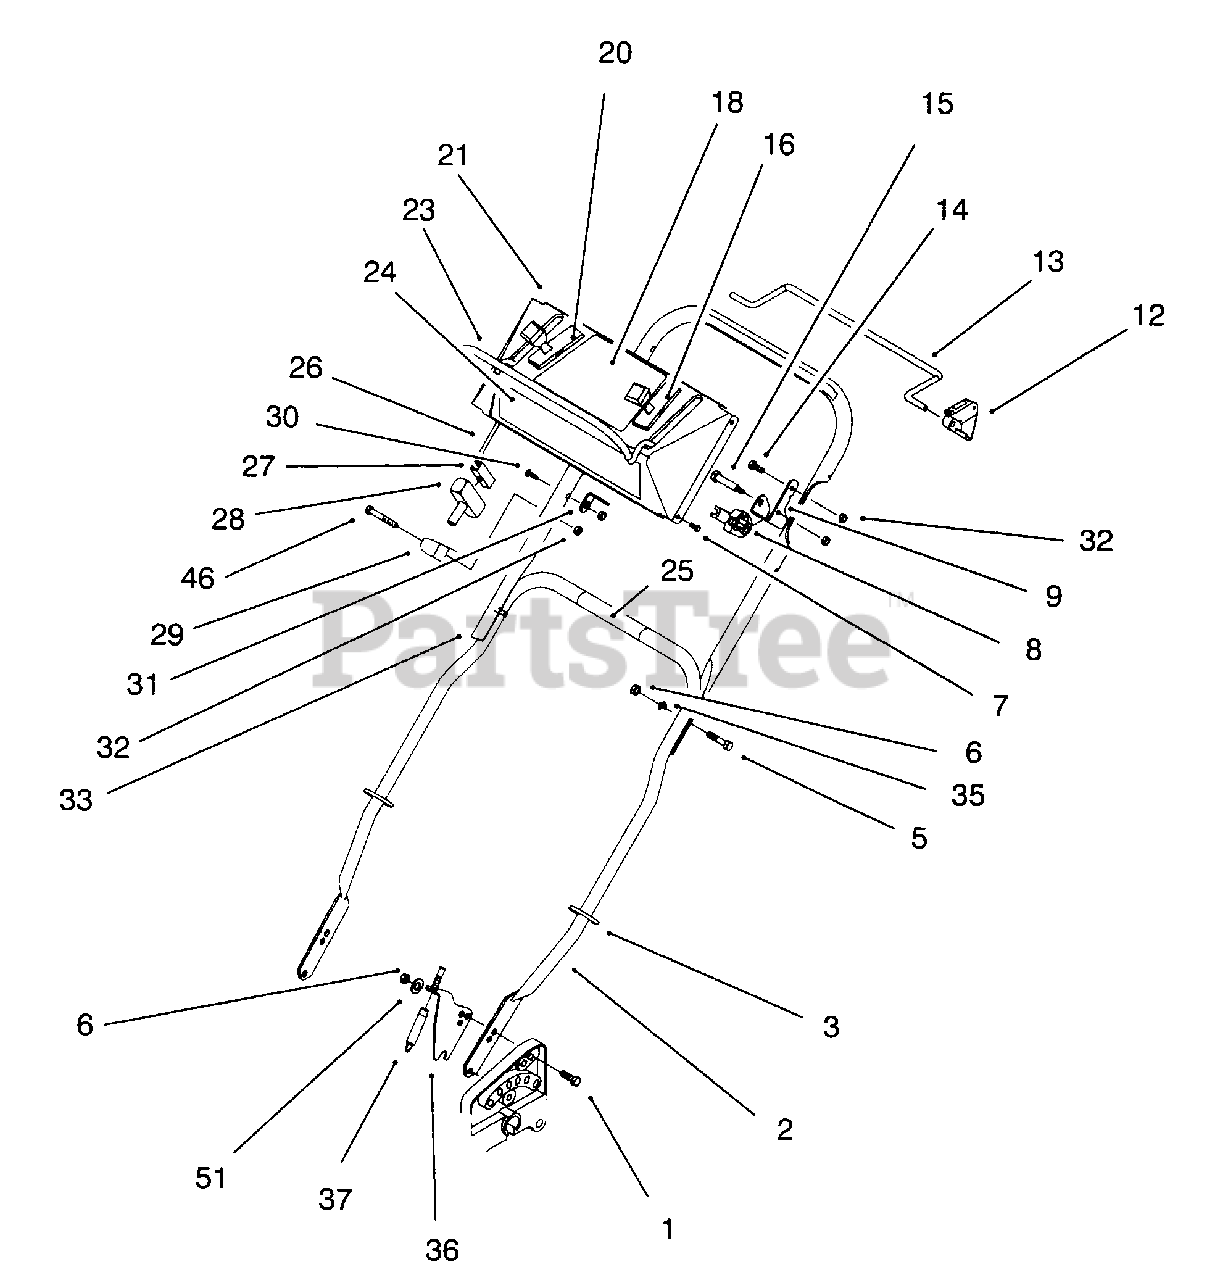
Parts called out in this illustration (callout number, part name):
1	Bolt-Carriage
2	Handle-Section Lower (Incl. Ref. #25)
3	Tie Strap
5	Screw-Hex Hd.
6	Nut-Lock
7	Screw-Phillips Hd.
8	Cam-Brake
9	Bracket-Bail Stop
12	Stop-Pivot
13	Bail-SP Control
14	Screw-Hex Hd. Cap
16	Cable-Throttle
18	Decal-Control Panel
20	Control-Speed Ground
21	Panel-Control (Incl. Ref. #18, & 24)
23	Bail-Engine Control
24	Decal-Console Front
25	Decal-Operation
26	Cable-Control
27	Clip-Rope Insert
28	Handle-Starter
29	Guide-Rope
30	Screw-Handle
31	Bracket-Cable Anchor
32	Nut-Lock
33	Handle-Upper
36	Bracket-Traction Cable
37	Cable-Traction
46	Screw-Hex Hd. Cap
49	Nut-Lock
51	Washer-Flat
